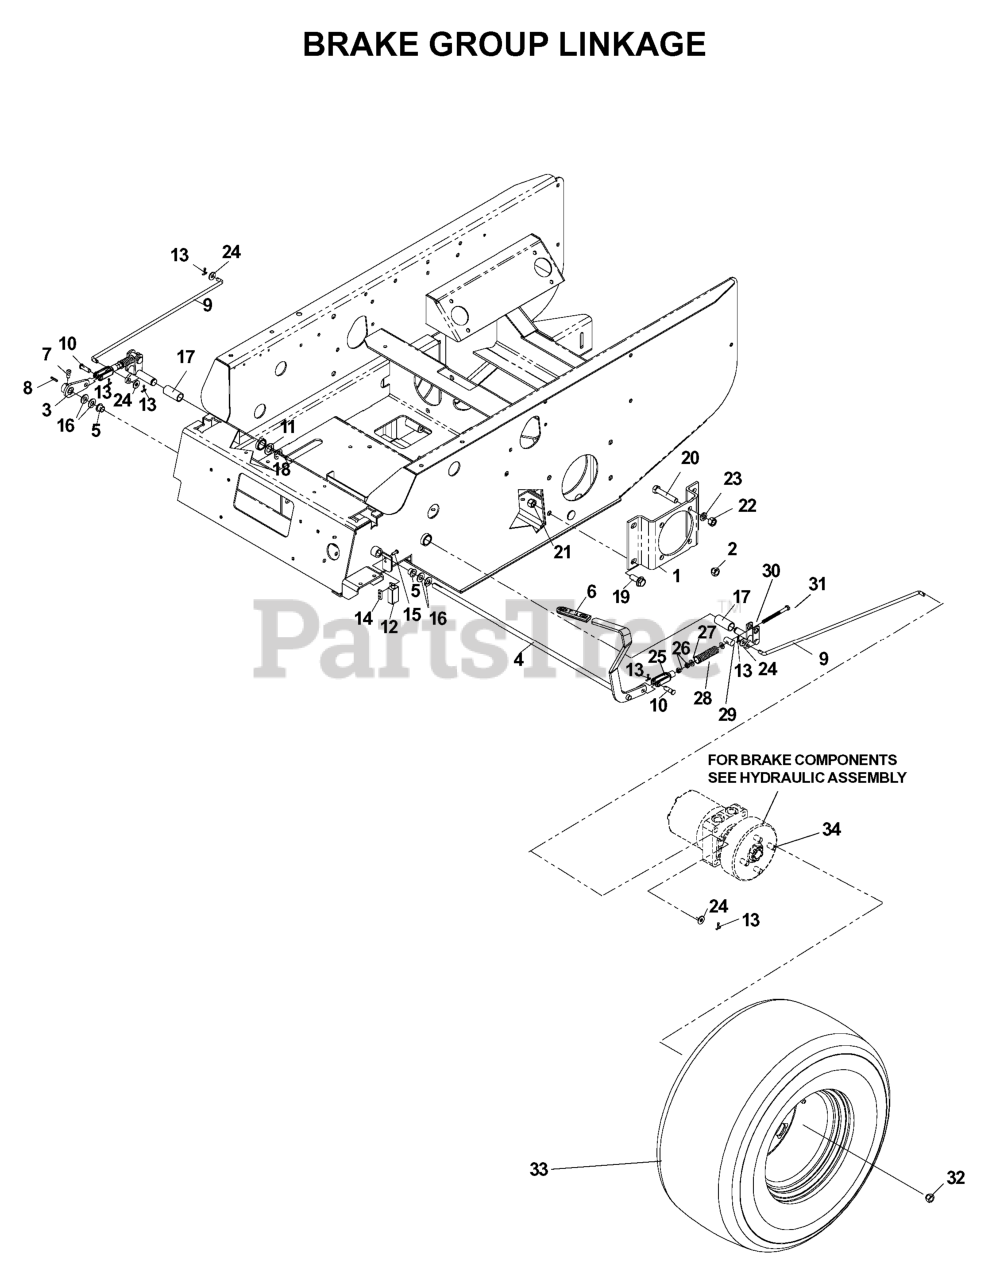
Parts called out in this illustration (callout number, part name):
1	MOTOR STANDOFF - PAINTED
2	LUG NUT 1/2F
3	BRAKE ARM WELDMENT
6	GRIP, PARK BRAKE
7	SCREW 5/16C X 5/8 SQ HEAD
9	BRAKE LINKAGE BAR
10	CLEVIS PIN 3/8 X 1 1/8
13	RP_COTTER PIN 1/8 X 3/4
14	TAPPED PLATE
15	SCREW #10-24 X 5/8
16	WASHER, 7/16 DISC SPRING
17	BRONZE BEARING
18	E RING 3/4
19	HCS 1/2C X 1 1/4 SERRATED HEAD
20	HCS 1/2C X 2 3/4
21	NUT 1/2-13 HEX NYLOC ZD
22	NUT HEX 1/2
23	WASHER 1/2" SPLIT LOCK
24	WASHER 5/16 FLAT
25	YOKE-3/8-24 PLTD
27	WASHER 3/8 SAE FLAT
29	TRUNION PIN
31	HCS 3/8F X SPECIAL
32	LUG NUT 1/2F
33	TIRE/WHEEL ASSY 26 X 12-12
34	WHEEL STUD 1/2-20X1-3/8 GR8 ZN
